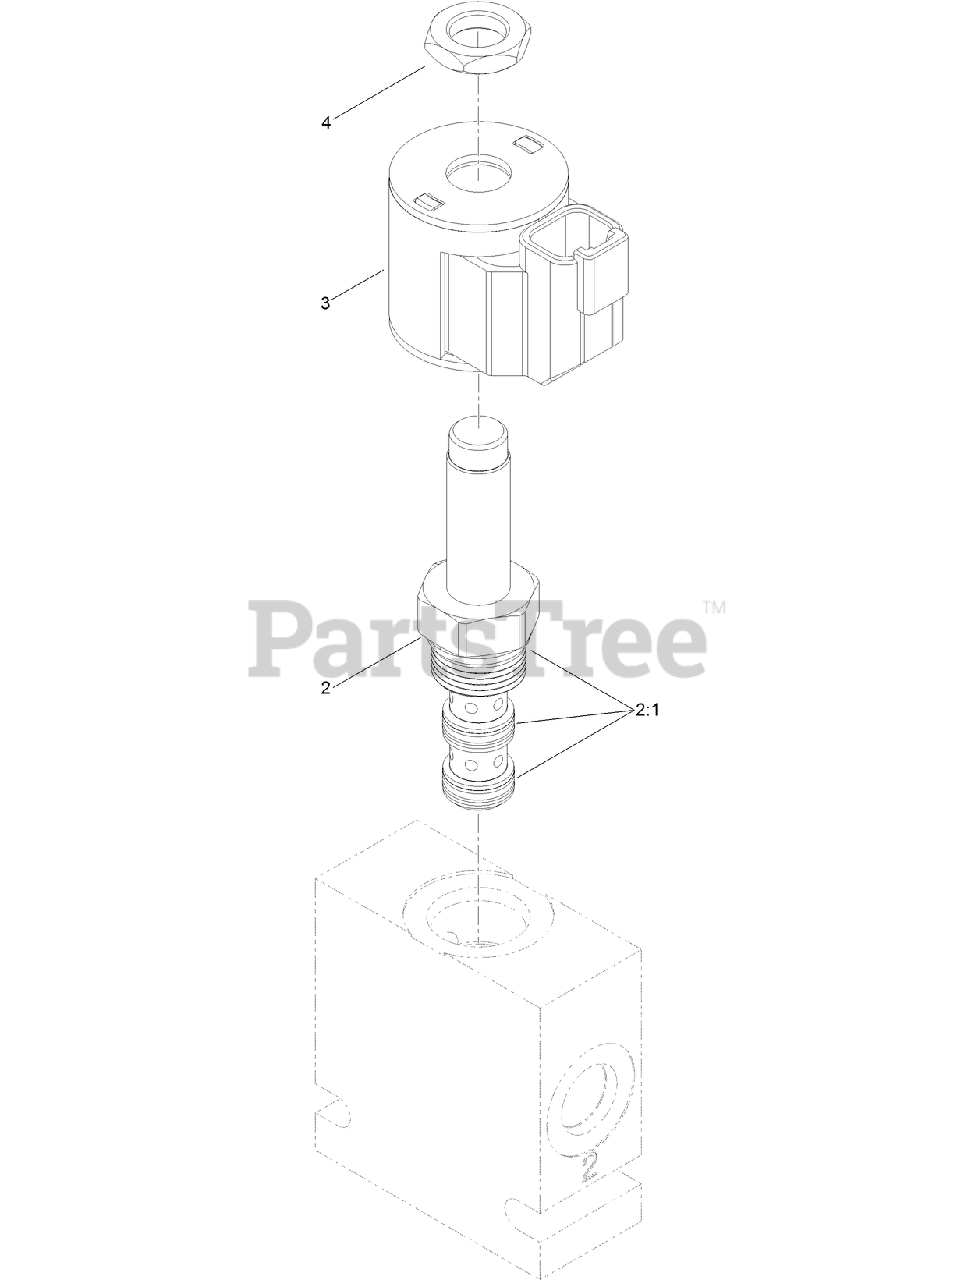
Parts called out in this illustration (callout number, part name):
2	Valve-3 Way
2:1	SEAL KIT
3	E COIL-12V DC
4	NUT-COIL
